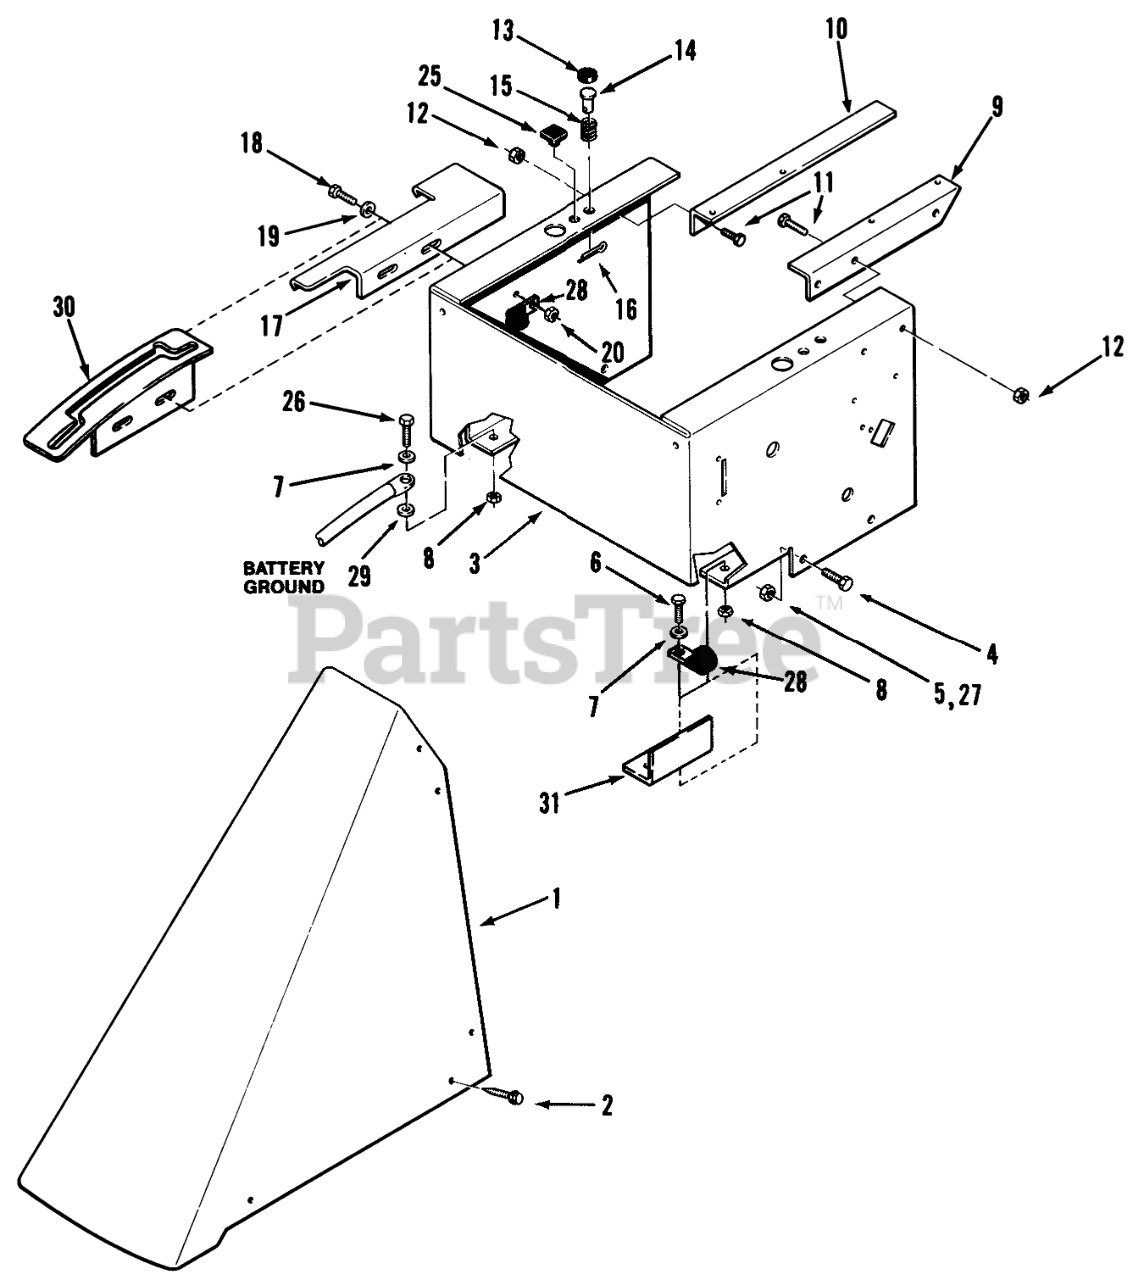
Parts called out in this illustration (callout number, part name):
1	COVER CONSOLE R
2	HEX WASHER STS
3	Seat Support
4	BOLR HWH 3/8-16X7/8
5	NUT
6	Bolt
7	WASHER 5/16 SAE
8	Nut
9	ANGLE TANK SUPP. R
10	ANGLE TANK SUPP. R
11	H H C S
12	Nut
15	SPRING
16	Cotter Pin
17	PLATE SHIFT R
18	Bolt
19	WASHER 5/16 SAE
20	Nut
25	BUMPER SJ5514 BLACK
26	Bolt
27	Nut
28	CLIP
29	Washer-Lock
30	Shift Quadrant 112-C Only
31	Bracket 112-C Only
